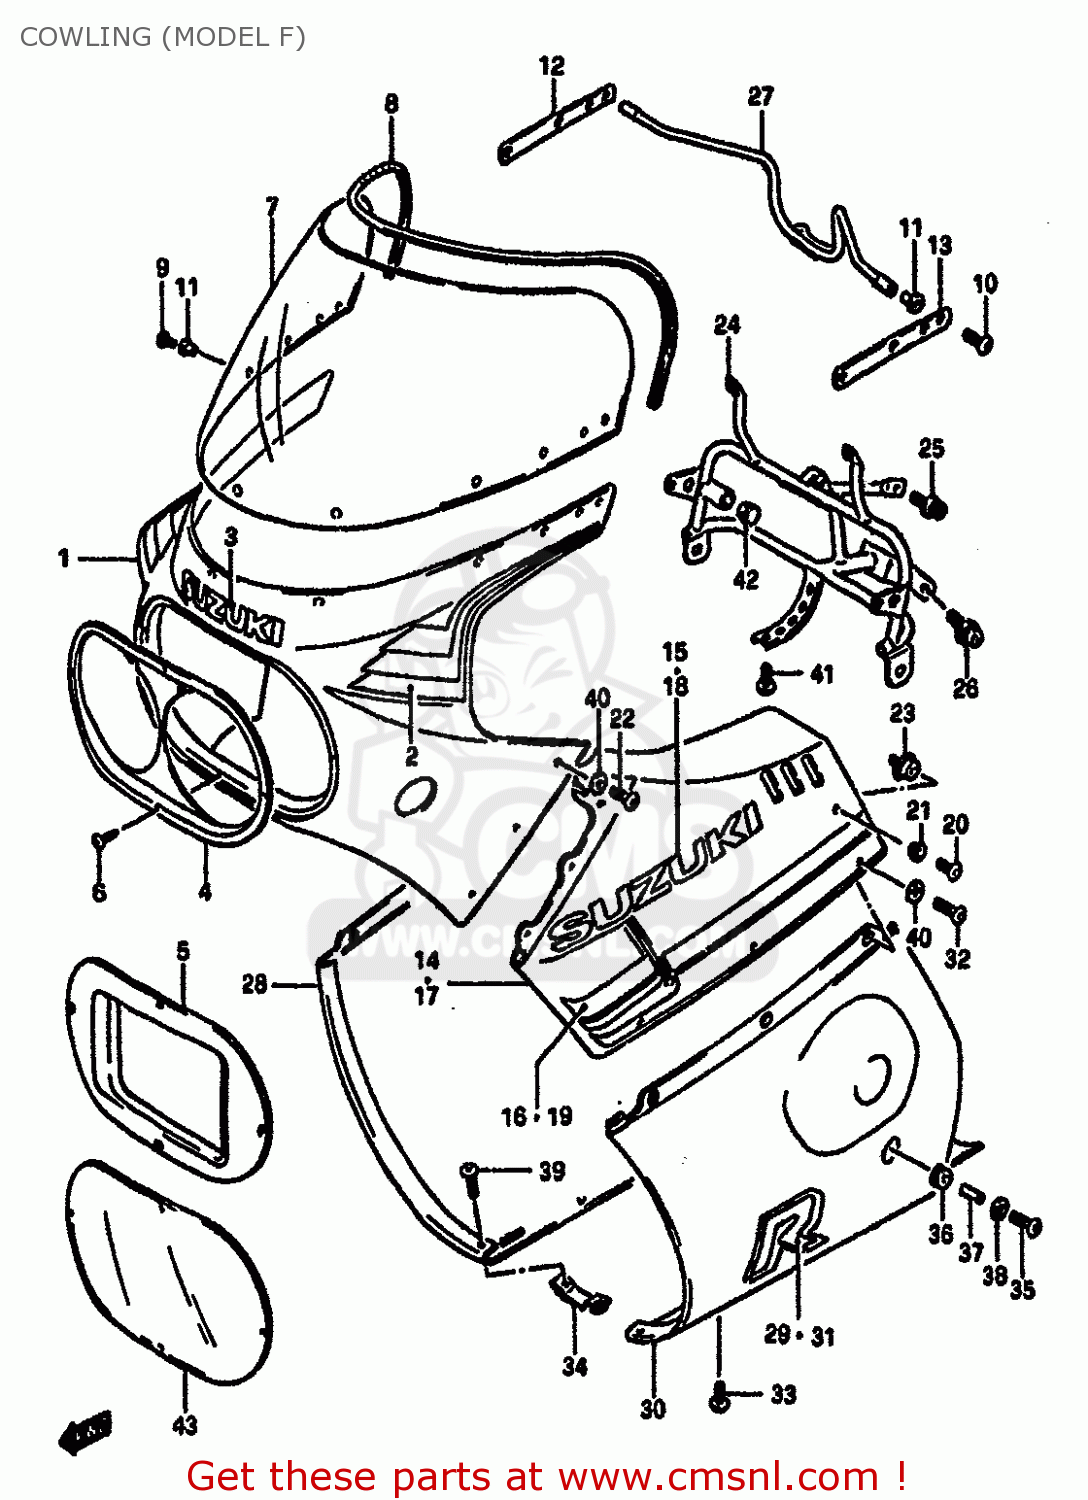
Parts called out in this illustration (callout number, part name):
1	BODY ASSY,COWLING (BLACK/RED)
2	TAPE SET,COWLING
3	EMBLEM,LEG SHIELD
4	COVER,COWLING FR
5	COVER,FRONT (RED)
6	SCREW
7	WINDOW,COWLING
8	MOLDING
9	SCREW(5X14)
10	SCREW(5X18)
11	NUT,COWLING SCREEN
12	PLATE,RR VIEW MIRROR,R
13	PLATE,RR VIEW MIRROR,L
14	COVER,SIDE RH (WHITE)
15	EMBLEM
16	TAPE SET,RH
17	COVER,SIDE LH (WHITE)
18	EMBLEM
19	TAPE SET,LH
20	SCREW(6X12)
21	WASHER
22	SCREW(6X16)
23	CUSHION,COWLING
24	BRACE,FRONT
25	BOLT
26	BOLT
27	BRACE,COWLING BODY RR
28	COWLING,LOWER
29	EMBLEM
30	COVER,COWL LH
31	EMBLEM
32	SCREW(6X16)
33	SCREW(6X16)
34	PLATE,LOWER COVER
35	SCREW(6X20)
36	CUSHION
37	SPACER
38	WASHER(6.5X18X1)
39	SCREW(6X12)
40	WASHER(6.5X15X1.0)
41	SCREW(6X16)
42	PLUG(OD:22)
43	COVER,HEADLAMP
